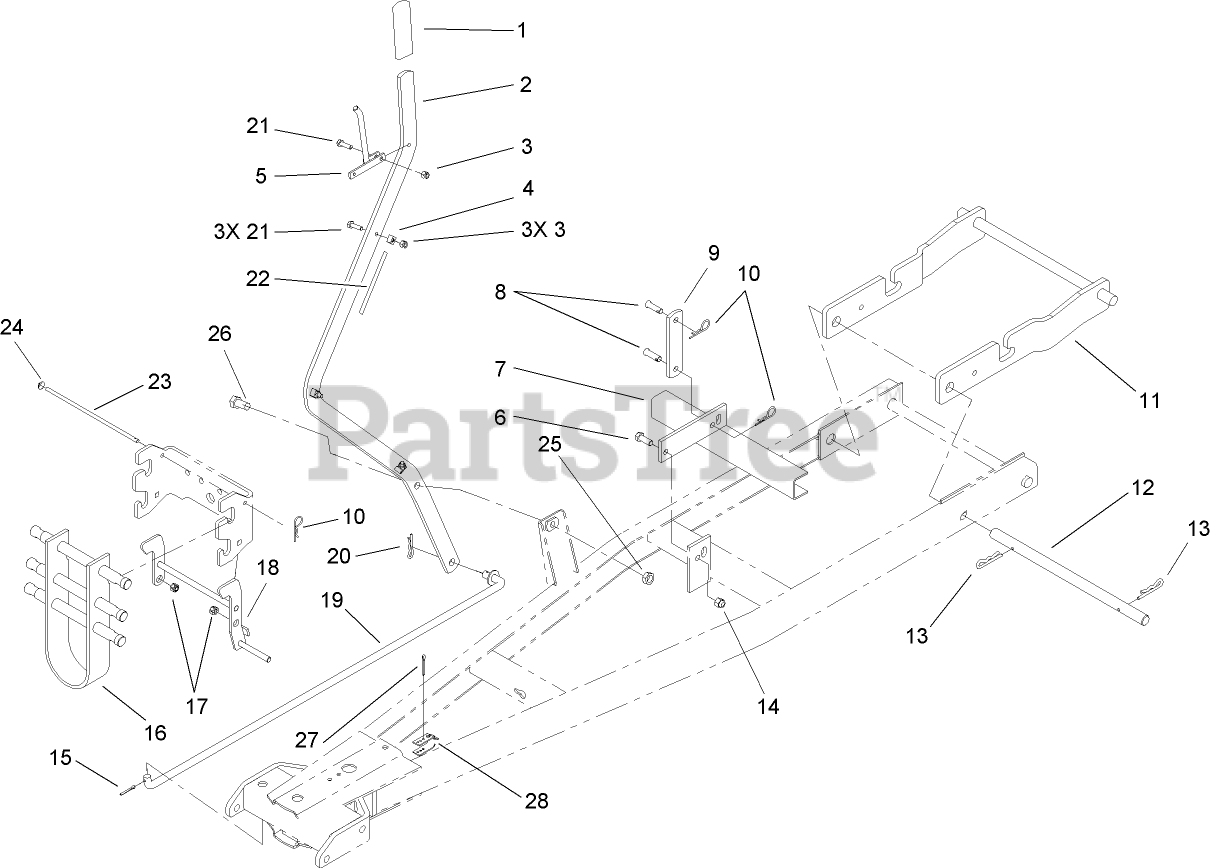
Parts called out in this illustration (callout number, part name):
1	GRIP
2	LEVER-BLADE,INDEX
3	NUT-LOCK
4	R-CLAMP
5	LEVER-INDEX
6	SCREW-HH
7	LIFT ASM
8	PIN-CLEVIS
9	LINK-LIFT
10	PIN-HAIR
11	DOZER EXT ASM
12	SHAFT
13	PIN-HAIR
14	NUT-LOCK, NI
15	PIN-COTTER
16	ANTI SWAY ASM
17	NUT-LOCK, NI
18	LATCH ASM
20	PIN-HAIR
21	SCREW-HH
22	CABLE-TENSION
23	ROD-STOP
24	NUT-SPEED
25	NUT-JAM
26	SCREW-HH
27	PIN-COTTER
28	BRACKET - CABLE END
